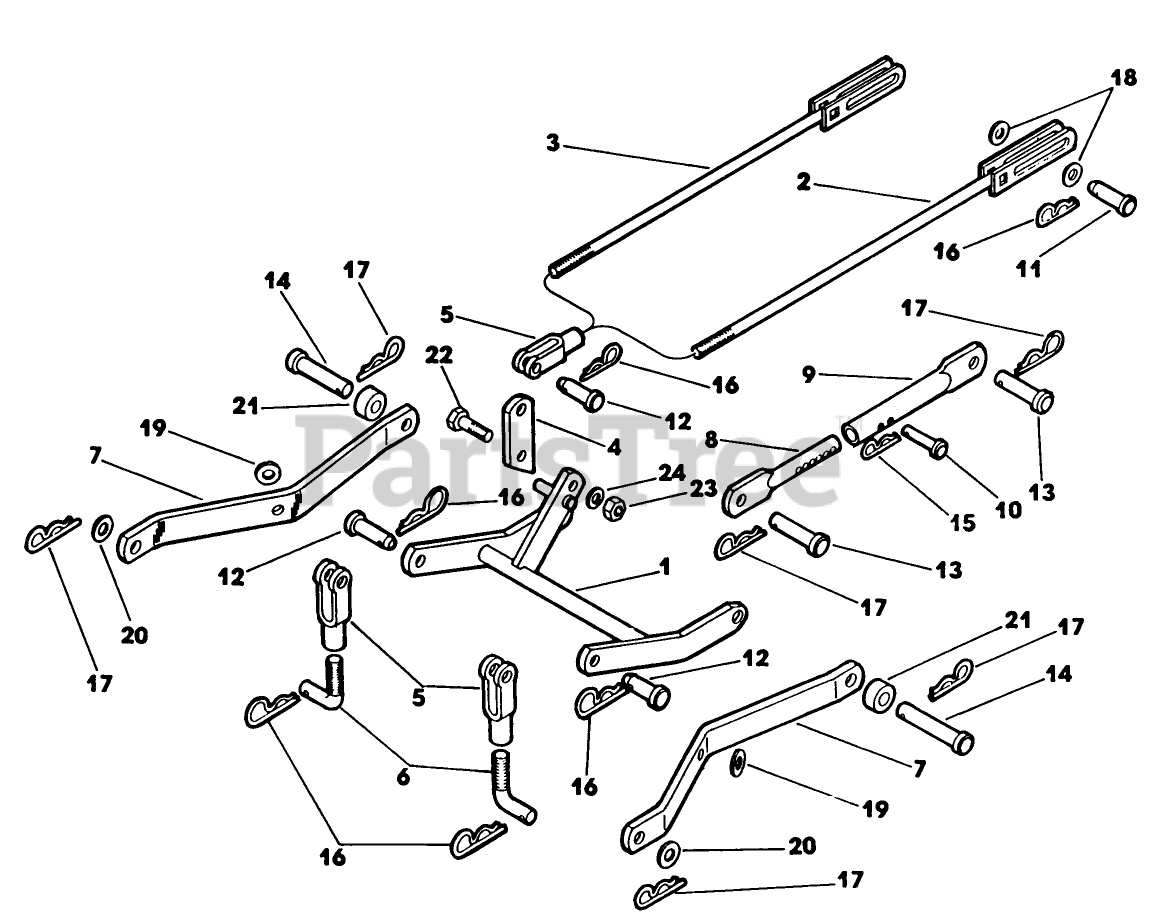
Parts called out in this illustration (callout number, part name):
2	ROD AY - LIFT
4	ARM-LIFT
7	LINK-LIFT
8	LIFT LINK-INSIDE
9	LIFT LINK-OUTSIDE
12	PIN CLEVIS
13	PIN-CLEVIS
15	PIN-HAIR
16	PIN - SPRING CLIP
